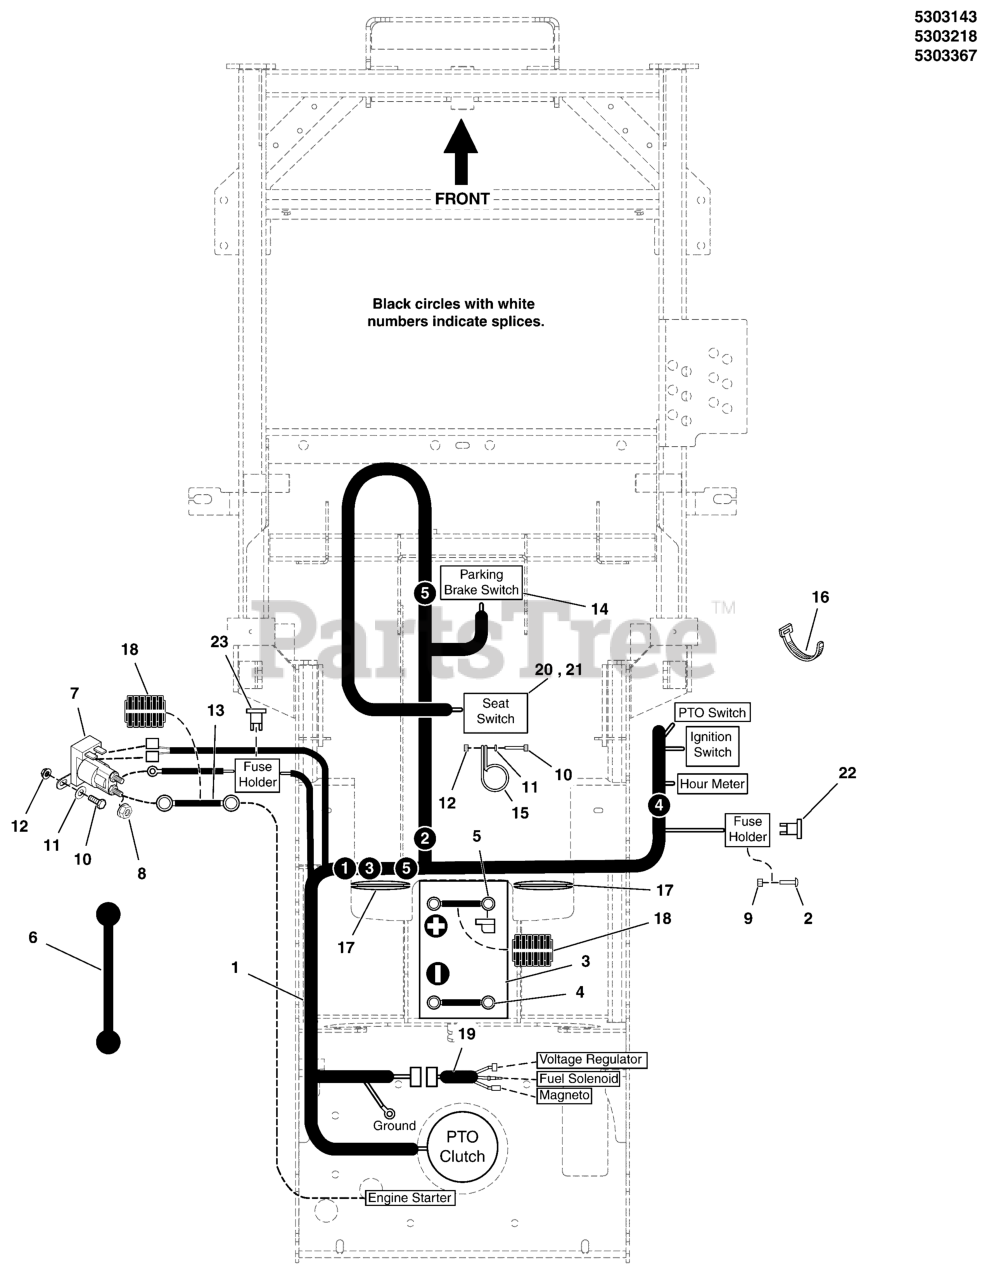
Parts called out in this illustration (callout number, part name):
1	WIRE HARNESS, MAIN, SM, ZTR
2	SCREW- #10-24 X 1/2 ROUND PHILLIPS
3	BATTERY, WET ( BCIU1, 350 CCA)
4	BATTERY CABLE, NEG, 14, 5/16-13/32
5	BATTERY CABLE, POS, 22, 1/4-5/16
6	STRAP-BLACK RUBB
7	SOLENOID, STD-BRACKET, 2-SPADE
8	NUT,1/4-20,KEPS,CONICAL WSHR,ZC/CL
9	NUT, #10-24 HEX NYLON LOCK
10	BOLT, 1/4-20 X 3/4 GD5 CZ
11	WASHER, 1/4 SAE
12	NUT, 1/4-20 HEX SERR. FLANGE
13	BATTERY CABLE, POS, 22, 1/4-5/16
14	SWITCH, DP NO/NC SNAP-IN
15	CLAMP, VINYL INSULATED, 1.00
16	TIE,SELF-LOCKING, 6"
17	GROMMET, 2" ID
18	WIRE LOOM, 3/8 ID X 18 IN
19	WIRE HARNESS, JUMPER, KAWI
20	SWITCH, NC, W/ BOLT-IN BASE
21	SWITCH, NC, W/ TWIST-IN BASE
22	FUSE, ATO-15 (15 AMP)
23	FUSE, ATO-20 (20 AMP)
